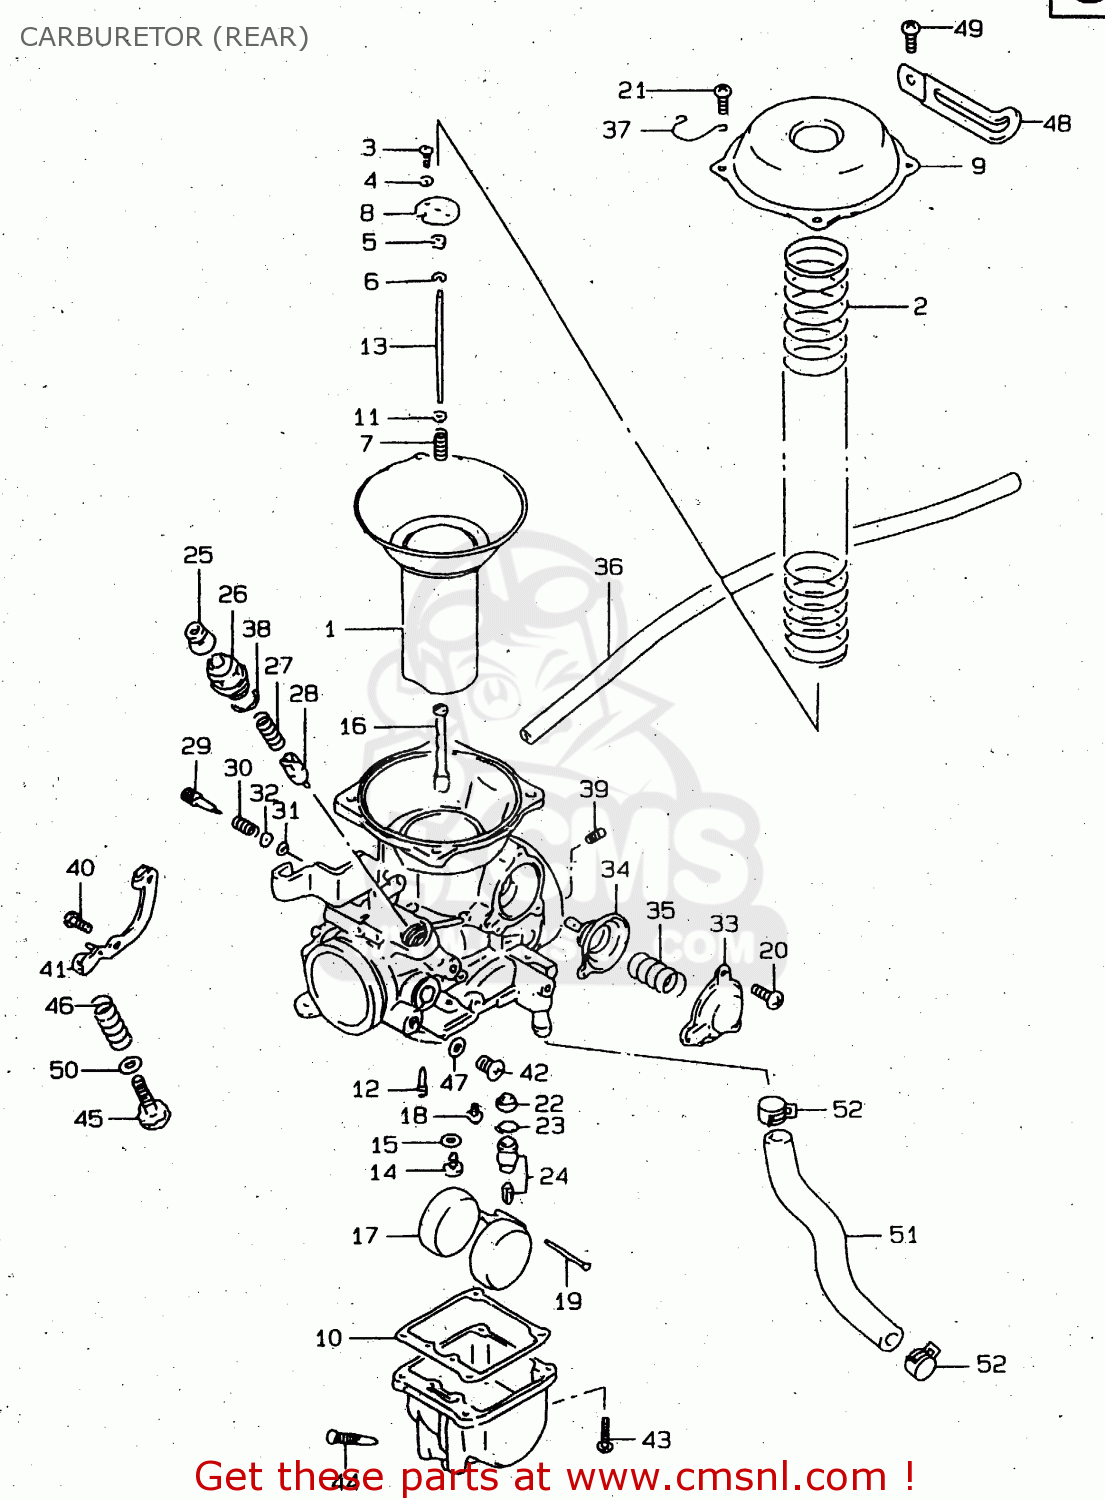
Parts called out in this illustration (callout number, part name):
1	DIAPHRAGM ASSY
2	SPRING,DIAPHRAGM
3	SCREW
4	WASHER,LOCK
5	RING
6	CLIP
7	SPRING
8	PLATE
9	COVER,DIAPHRAGM
10	GASKET,FLOAT CHAMBER (NAS)
11	WASHER
12	JET,PILOT(45)
13	NEEDLE,JET
14	JET,MAIN(107.5)
15	WASHER
16	JET,NEEDLE(P-3)
17	FLOAT
18	SCREW
19	PIN,FLOAT
20	SCREW
21	SCREW
22	FILTER
23	O-RING,NEEDLE VALVE
24	VALVE ASSY,NEEDLE
25	CAP
26	HOLDER,GUIDE
27	SPRING
28	PLUNGER,STARTER
29	SCREW,PILOT
30	SPRING
31	O RING,PILOT AIR SCREW
32	WASHER
33	COVER
34	DIAPHRAGM ASSY
35	SPRING
36	HOSE(5X8.2X600)
37	CLIP
38	O RING
39	JET,PILOT(70)
40	SCREW
41	LEVER ASSY
42	SCREW(5X6)
43	SCREW
44	SCREW,DRAIN
45	ADJUSTER
46	SPRING
47	GASKET,DRAIN PLUG (NAS)
48	CLAMP(L:65)
49	SCREW
50	WASHER
51	HOSE,FUEL PUMP & CARBURETOR
52	CLIP
